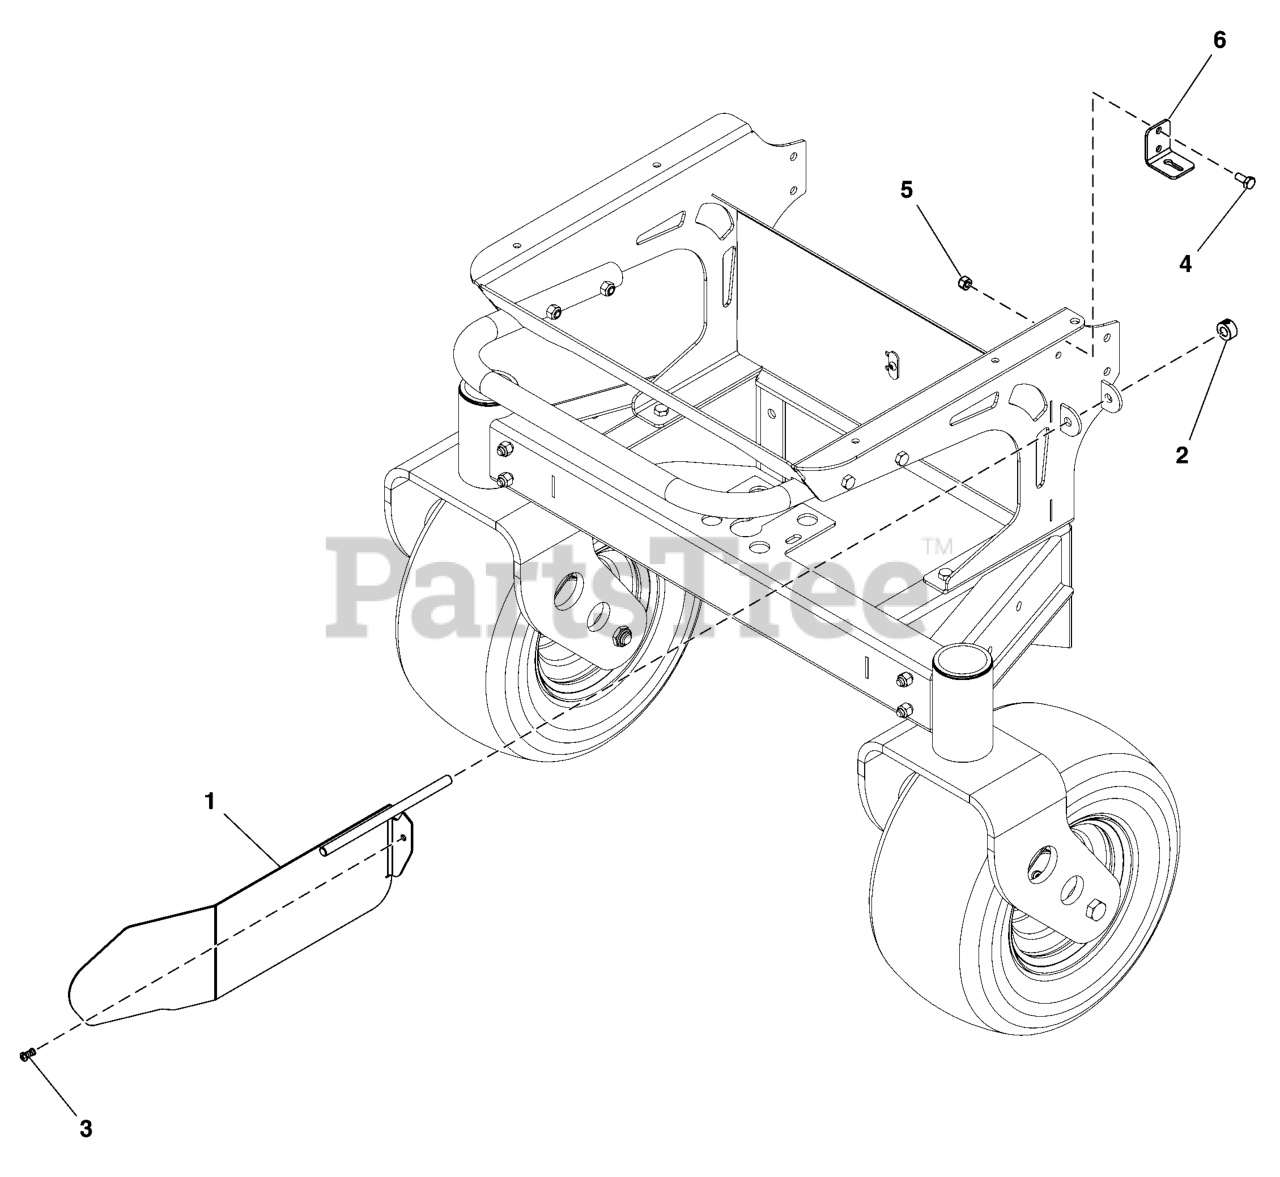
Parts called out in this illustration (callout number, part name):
1	WELD, DIVERTER SHIELD
2	COLLAR, SHAFT .375ID X .750OD X .375WD
3	FITTING, SWIVEL ACCUWAY
4	SCR-CAP, HEX .250"-20 X .625" SS188
5	NUT-HEX-NYLK, .250"-20 SS188
6	BRACKET, L-SHAPE DIVERTER CABLE
